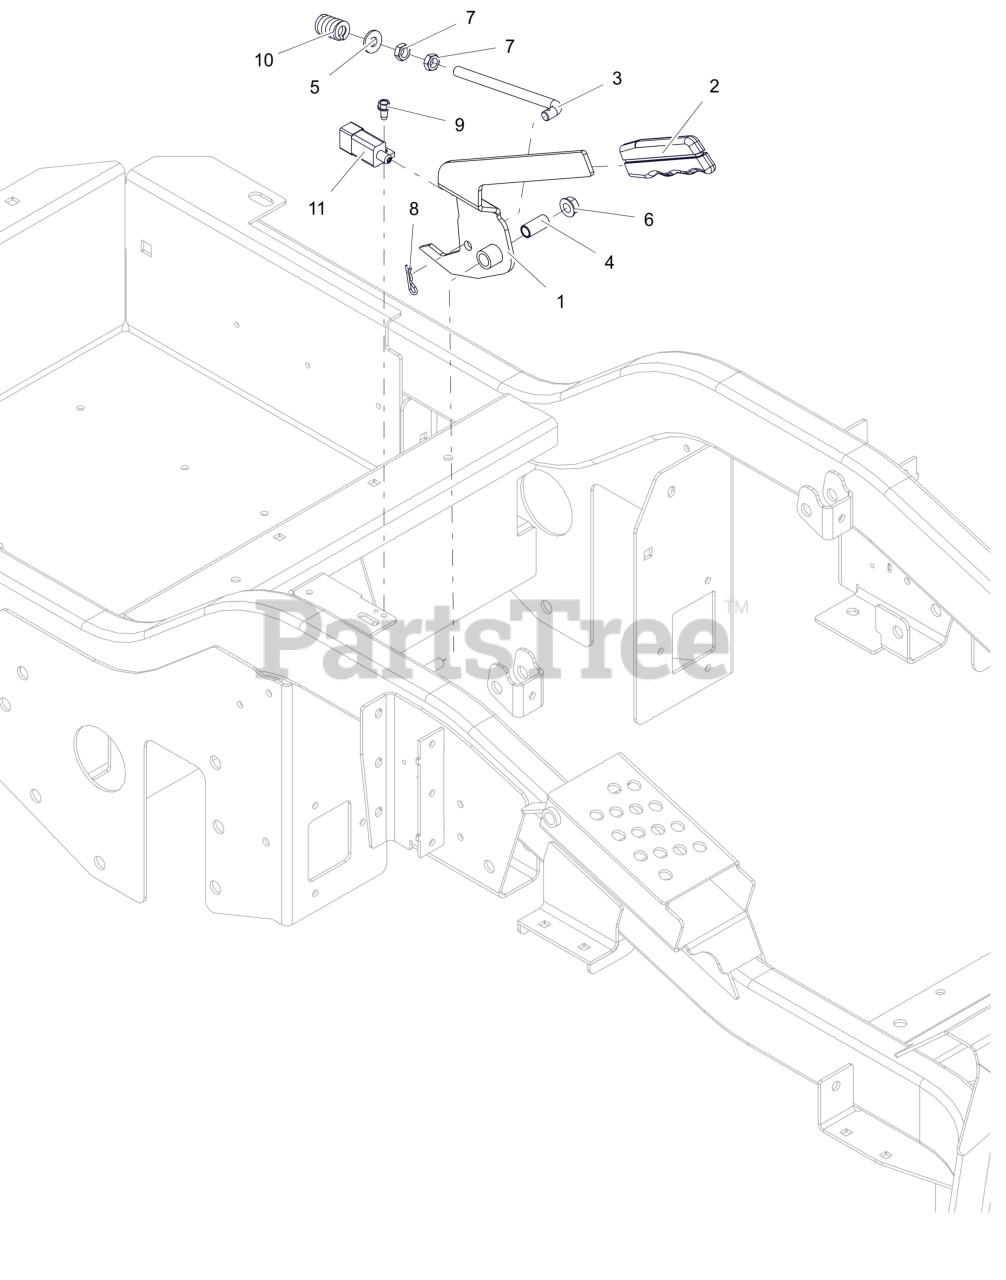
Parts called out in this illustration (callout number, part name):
1	WLDMT, INTERLOCK (BLACK)
2	GRIP, PARKING
3	ROD, OVER CENTER
4	BSHG-SLV .385X.500X1.045
5	WSHR,FLT .375X.875X.083 ZCC
6	NUT-LK-CTR-FLG .375-16 GF ZCC
7	NUT-JAM .375-16 G2 ZCC
8	PIN, HAIR #213 .08X1.19 ZCC
9	SCR-TAP .25-20X.50 HWH ZCC
10	SG-COMP .187X.56X1.62
11	SWITCH, BRAKE NO-NC-POST AND HOLE
